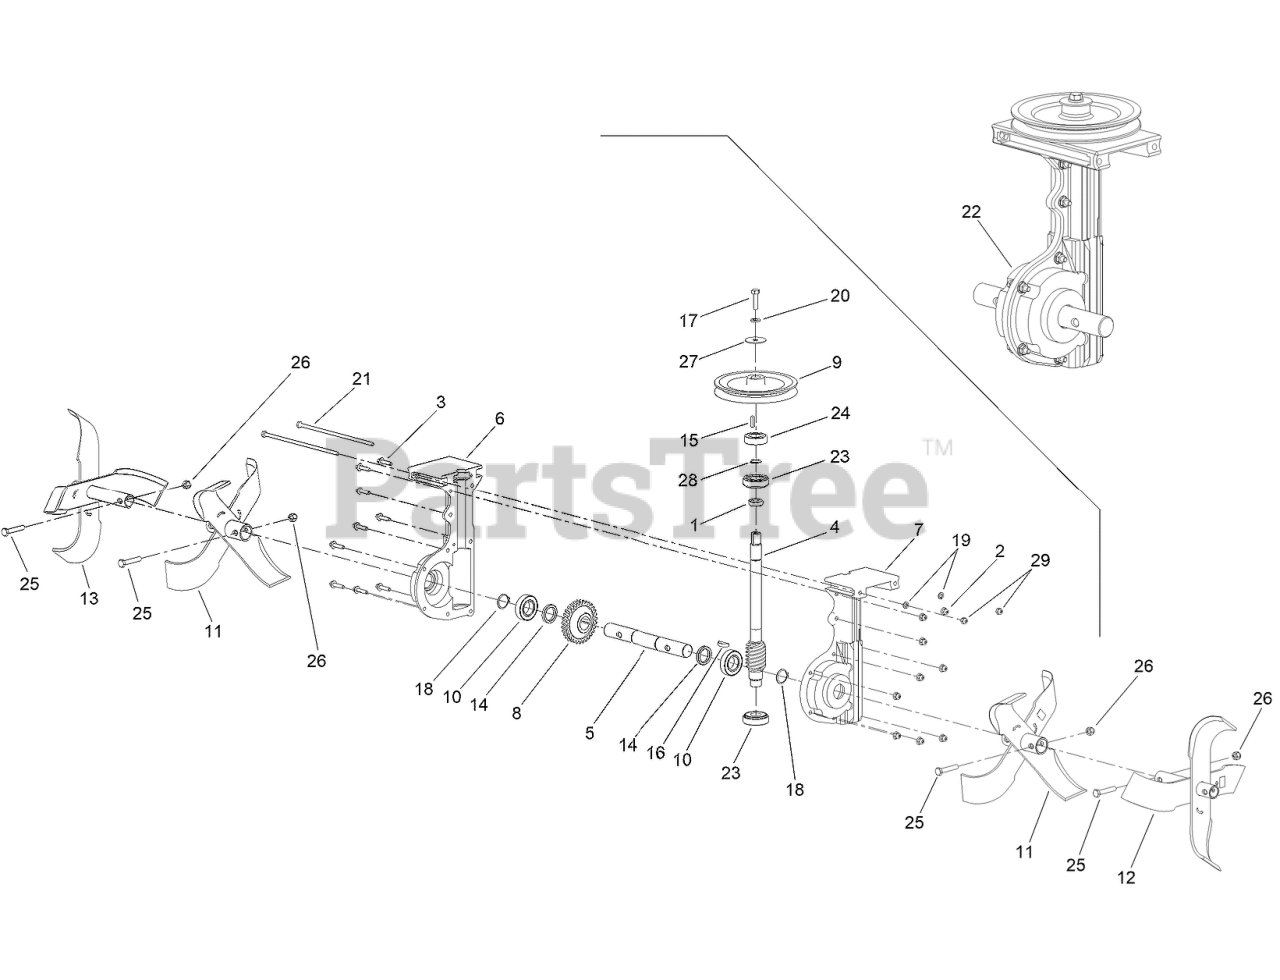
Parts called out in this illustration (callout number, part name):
1	SPACER-INPUT
2	NUT-HEX
3	SCREW-RHF
4	DRIVESHAFT-WORM
5	DRIVESHAFT-TINE
6	CASTING-RIGHT
7	CASTING-LEFT
8	GEAR-TRANSMISSION
9	PULLEY-TRANSMISSION
10	BEARING-OUTPUT
11	TINE-INNER
12	TINE-OUTSIDE LEFT
13	TINE-OUTSIDE RIGHT
14	SPACER-OUTPUT
15	KEY-SQUARE
16	KEY-HALFMOON
17	SCREW-HHCS
18	SNAP RING
19	WASHER-LOCK
20	WASHER-LOCK
21	SCREW-HHCS
22	TRANSMISSION ASM
23	BEARING-ROLLER
24	BEARING-ROLLER
25	SCREW-HHCS
26	NUT-HEX
27	WASHER-FLAT
28	RING-RETAINING
29	NUT-HEX
